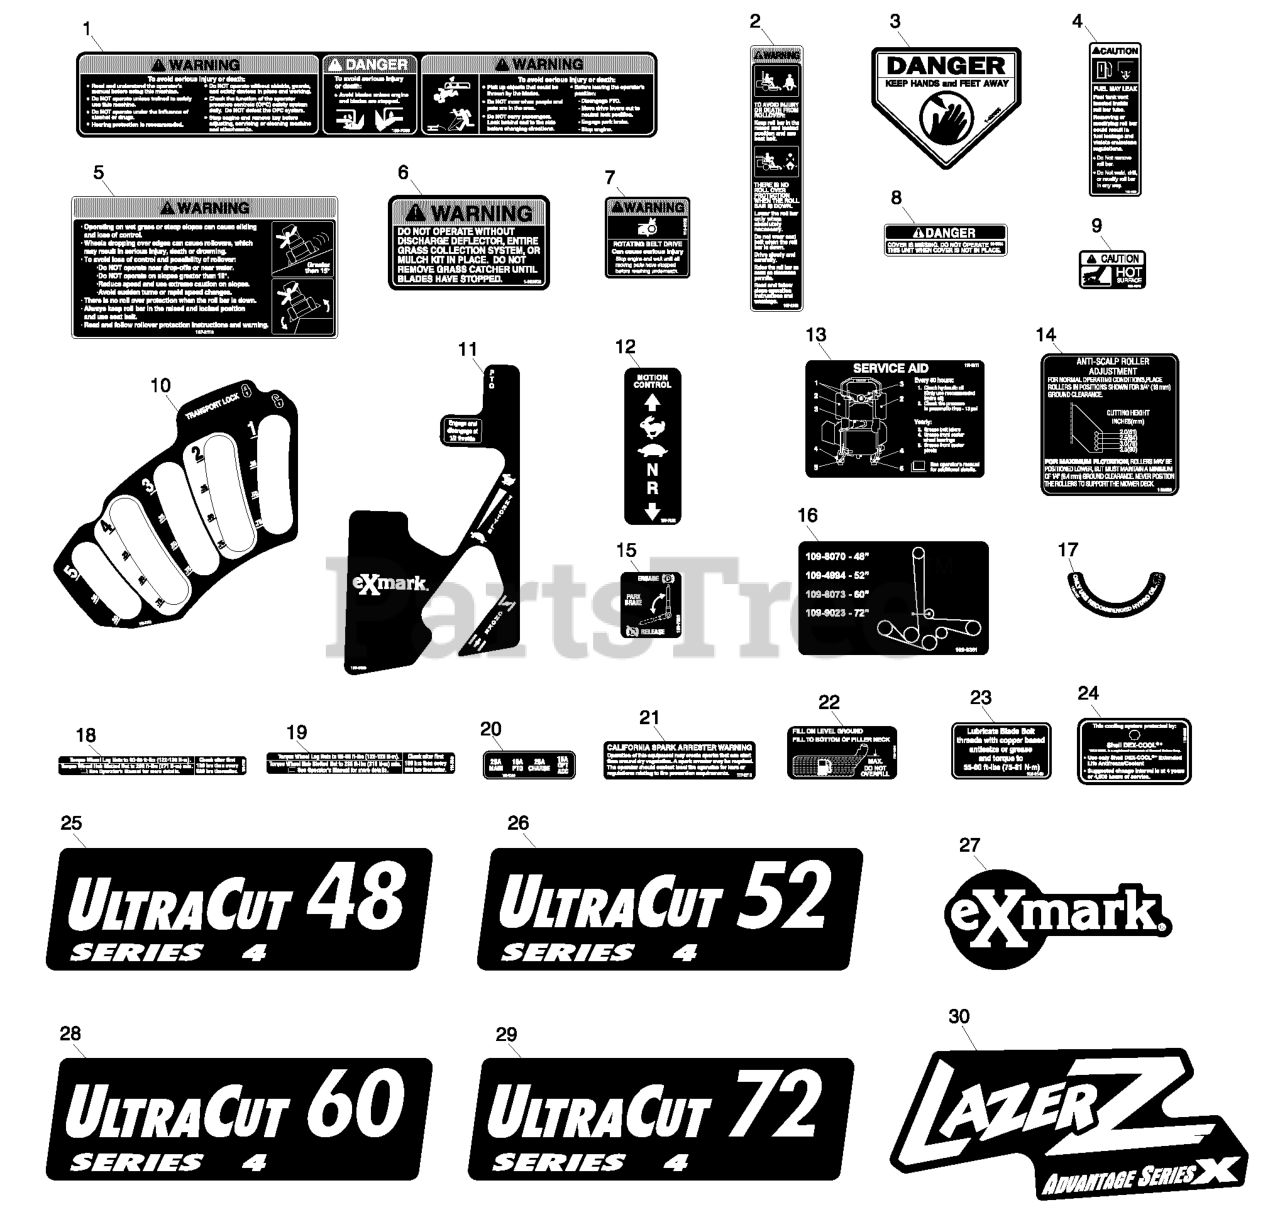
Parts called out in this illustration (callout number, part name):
1	DECAL-CONSOLE
2	DECAL-WARNING, FOLDING RO
3	DECAL-DANGER
4	DECAL-CAUTION
5	DECAL-WARNING
6	DECAL-WARNING, DISCHARGE
7	DECAL-BELT DRIVE
8	DECAL-COVER, MISSING
9	DECAL-CAUTION
10	DECAL-HOC
11	DECAL-CONTROL PANEL
12	DECAL-MOTION CONTROL
13	DECAL-SERVICE AID
14	DECAL,ANTISCALP
16	DECAL,BELT ROUTING
17	DECAL-HYDRO OIL
18	DECAL-HUB, WHEEL
20	DECAL-FUSE
21	DECAL-ARRESTER, SPARK
22	DECAL-FUEL FILL
23	DECAL,BOLT TORQUE
24	DECAL,SHELL COOLANT
25	DECAL,ULTRACUT 48 SERIES
26	DECAL,ULTRACUT 52 SERIES
28	DECAL,ULTRACUT 60 SERIES
29	DECAL,ULTRACUT 72 SERIES
30	DECAL,LAZER ASX LOGO
